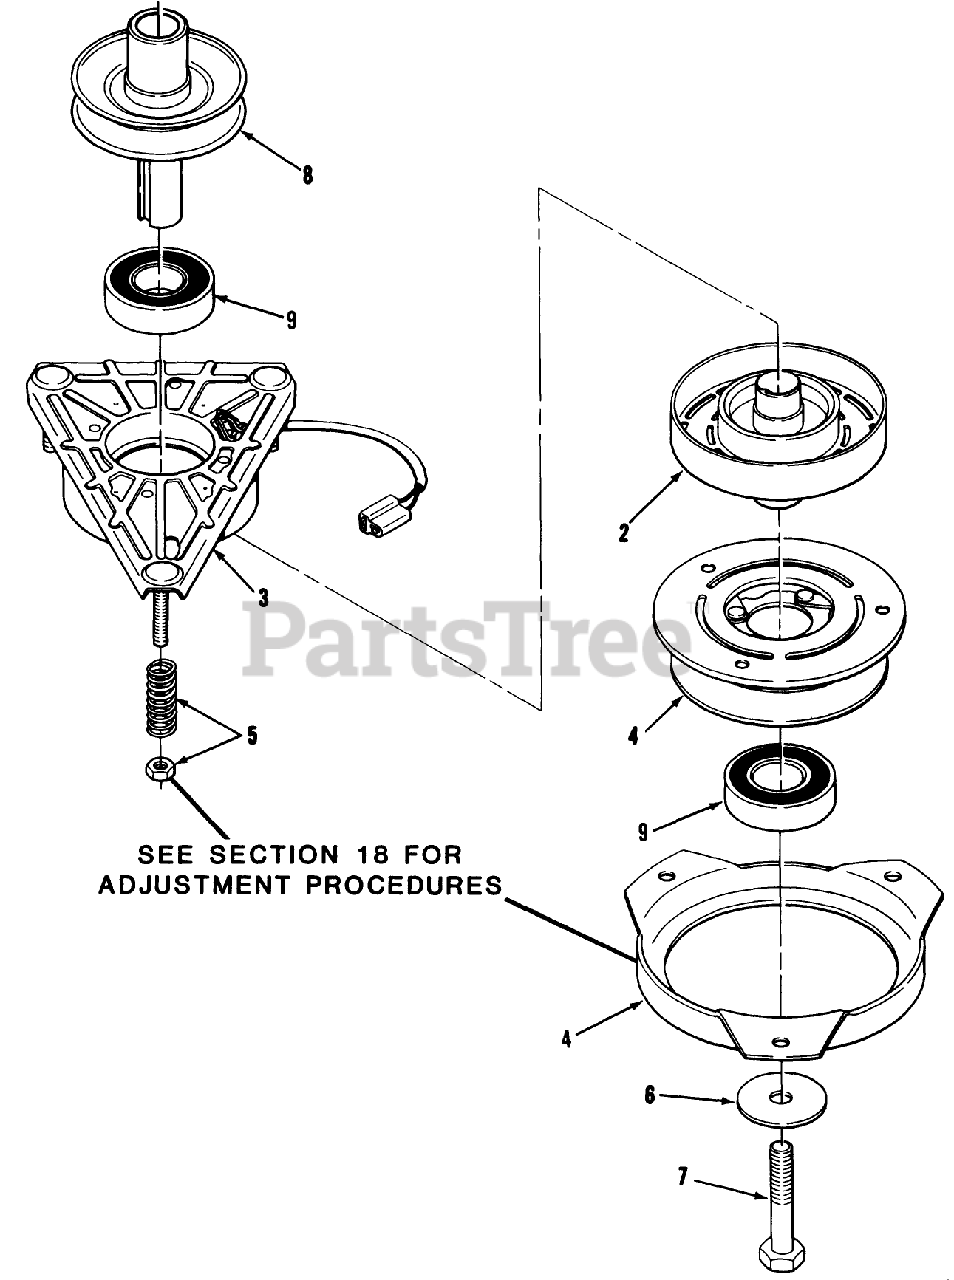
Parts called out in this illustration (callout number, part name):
2	Rotor Assy
3	Field Assy (Includes one of item 9)
4	Armature and pulley Assy (Includes one of item 9 and Brake Plate)
5	ACCESS SPRING & NUT
6	WASHER
7	HHCS M10X1.5X120
8	PULLEY-ENGINE
9	BEARING-ELEC CLUTCH
